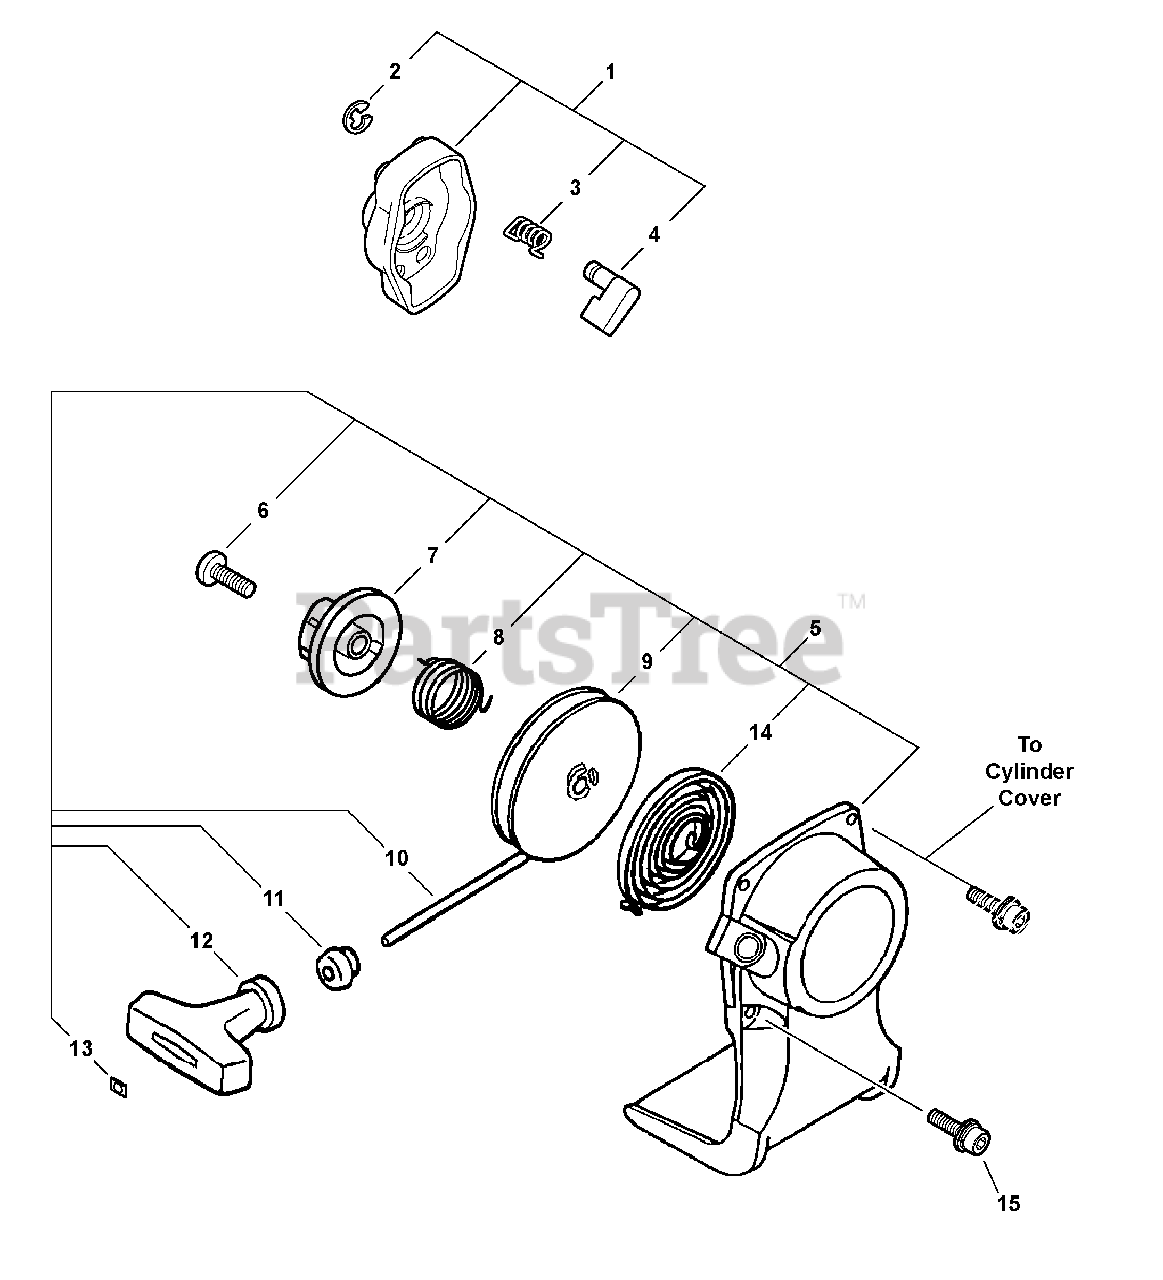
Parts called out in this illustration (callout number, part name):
1	PAWL ASSY, STARTER
2	E-RING 4
3	SPRING, RETURN
4	PAWL, STARTER
5	STARTER, RECOIL
6	SCREW
7	PLATE, CAM (NLA SEE PB 15-06)
8	SPRING, TORSION
9	REEL, ROPE
10	ROPE, STARTER 3×700
11	GUIDE, ROPE
12	GRIP, STARTER
13	RETAINER, ROPE
14	SPRING, RECOIL
15	BOLT 4×16
